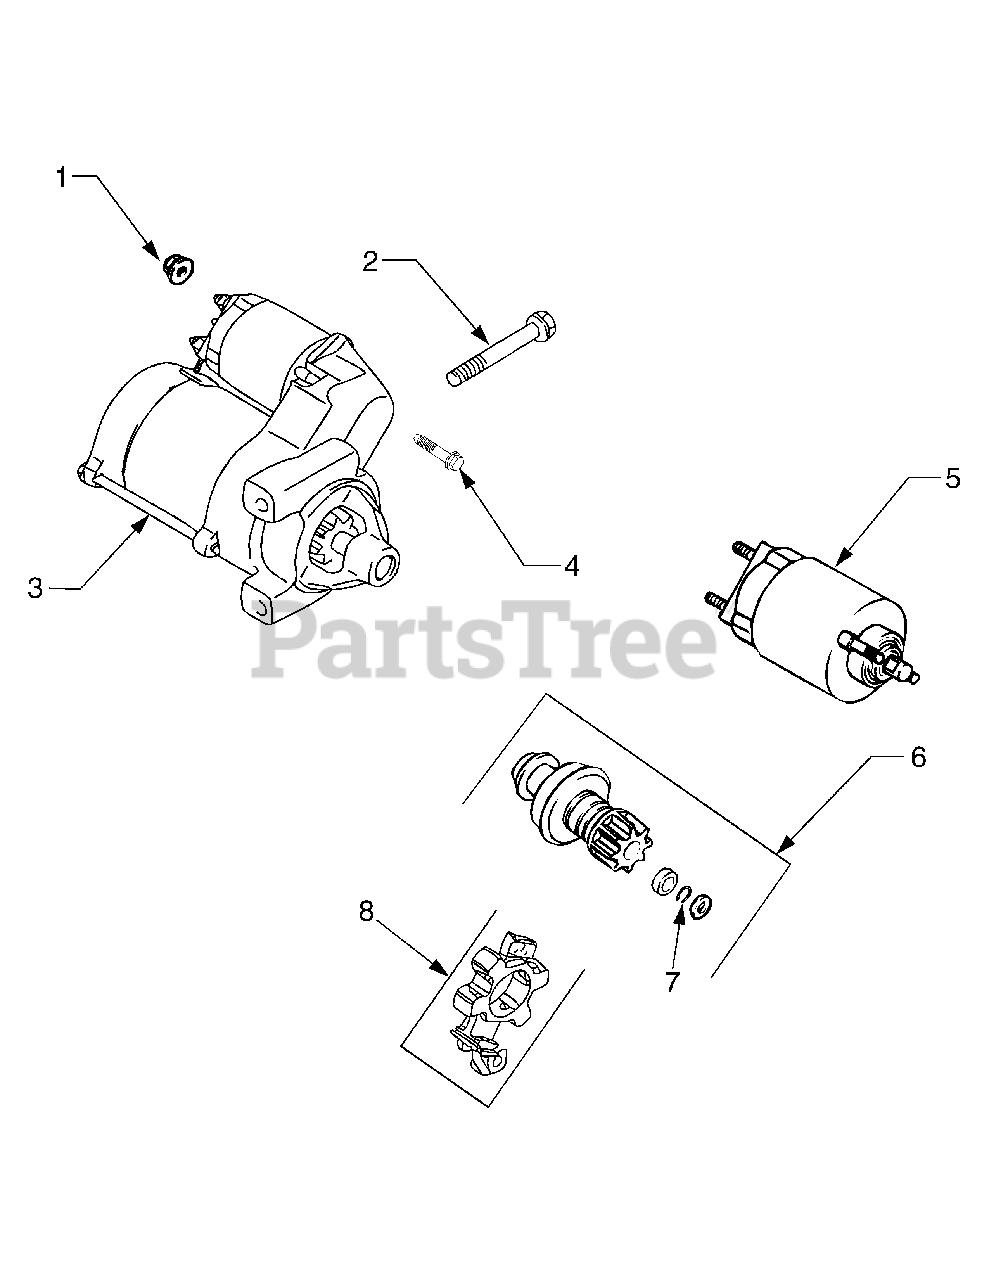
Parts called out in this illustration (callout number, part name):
1	Nut, Hex Flange M8 x 1.25"
2	Screw, Hex Flange M8 x 1.25 x 80
3	Starter, Solenoid Shift Assembly (Includes 4-8)
4	Screw, External Torx Hd.
5	Kit, Solenoid (Includes 4)
6	Kit, Pinion Drive (Includes 7)
7	Ring, Retainer
